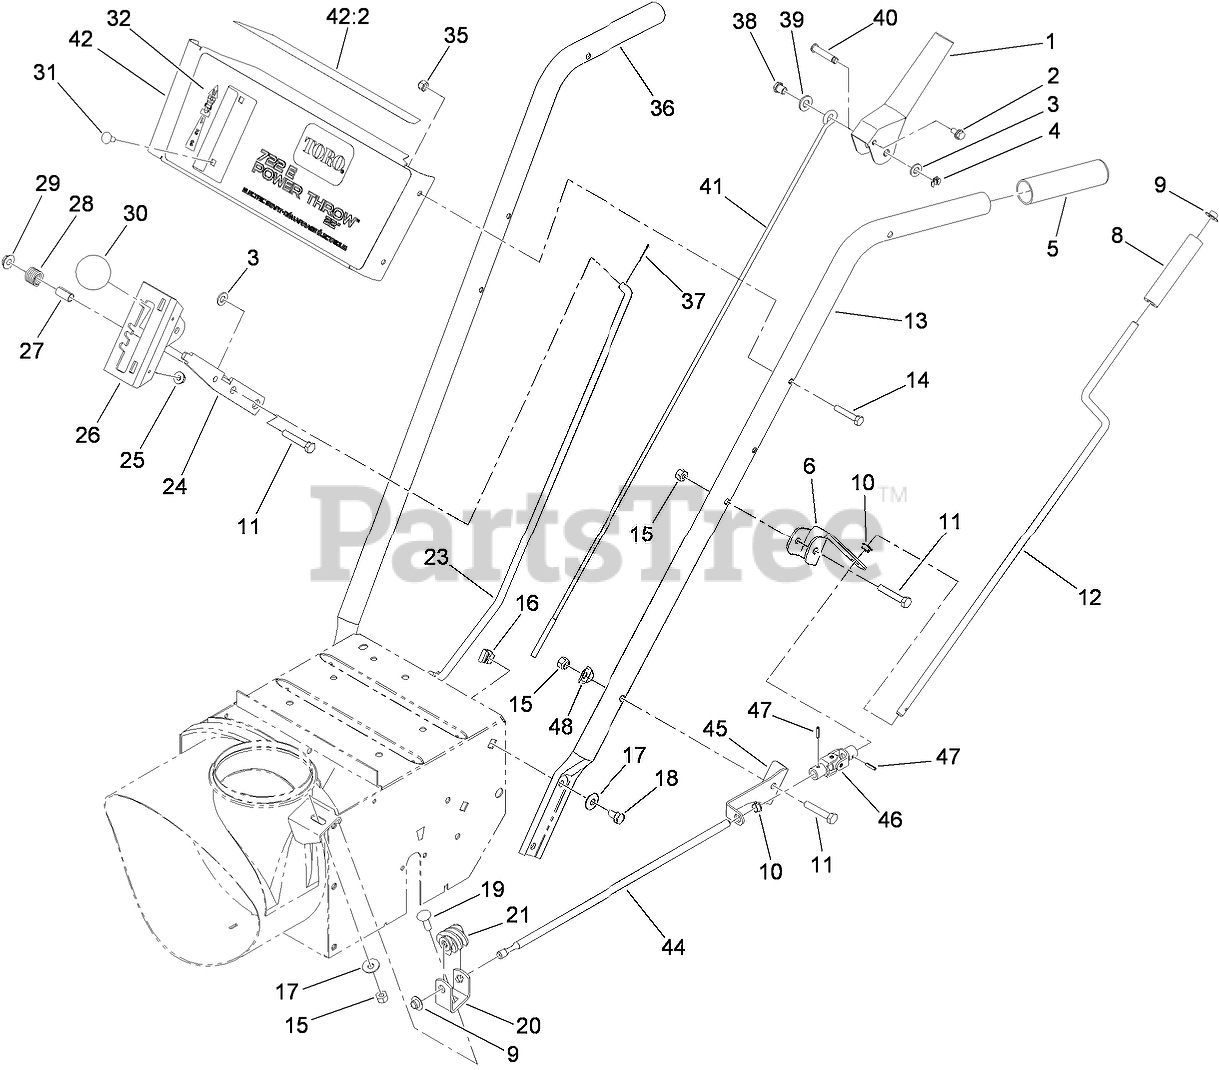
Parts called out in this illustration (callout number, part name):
1	HANDLE-CONTROL
2	SCREW-HHF
3	WASHER-PLAIN
4	RING-CLIP
5	GRIP-HANDLE
6	BRACKET-ROD, UPPER CHUTE
8	GRIP-CONTROL, CHUTE
9	RETAINER-PUSH ON
10	Bushing
11	SCREW-HH
12	ROD-CHUTE, UPPER
13	HANDLE-LEFT
14	SCREW-HH
15	NUT-LOCK, NI
17	WASHER-BELLEVILLE
18	SCREW-HH
19	SCREW-CARR
20	BRACKET-WORM
21	GEAR-WORM, CHUTE
23	ROD-SELECTOR, SPEED
24	Selector-Speed
25	NUT-HF
26	MOUNT-SELECTOR, SPEED
27	SPACER
28	SPRING
29	NUT-HF
31	SCREW-CARR
32	DECAL-PANEL, CONTROL
35	NUT-LOCK, NI
36	HANDLE-RIGHT
37	PIN-COTTER
38	POST-MOUNTING, LINKAGE
39	WASHER-FLAT
40	PIN-LEVER, CONTROL
41	LINK-UPPER
42	ESCUTCHEON PANEL ASM
42:2	DECAL-ESCUTCHEON, BACK
44	ROD-CHUTE, LOWER
45	BRACKET-ROD, LOWER
46	JOINT-UNIVERSAL
47	PIN-ROLL
48	WASHER
